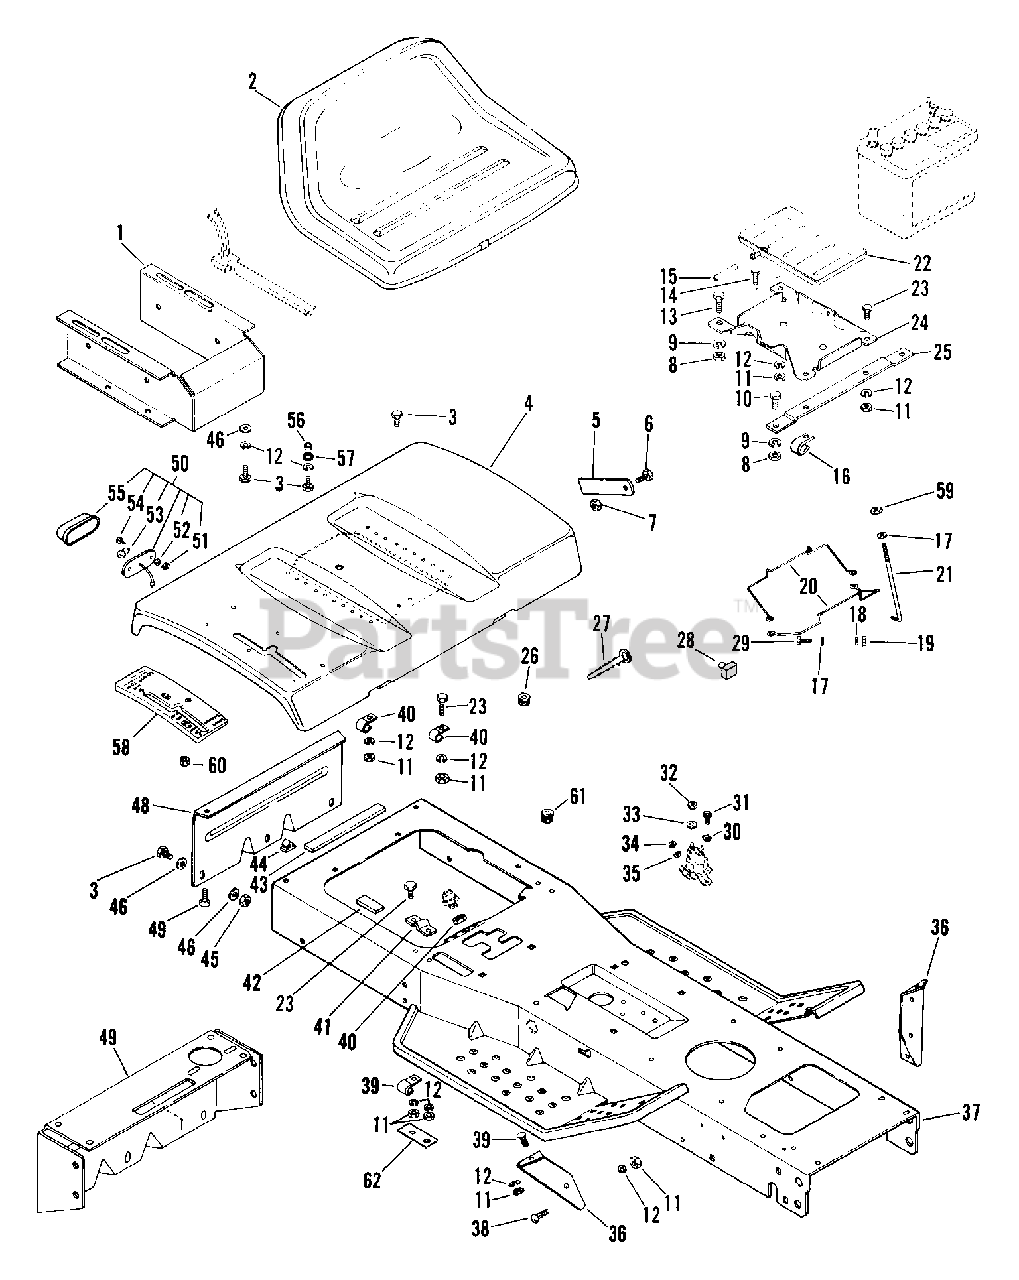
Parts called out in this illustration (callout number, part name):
1	SEAT FRAME
2	SEAT V-350
2	SEAT-V450
3	BLT-HEX .31-18X.75 PL GR5
4	REAR DECK
5	CATCH,DECK
6	BLT-HEX .38-16X.63 PL GR2
7	NUT-LK-JAM-CTR .375-16 PL
8	NUT-HEX .375-16
9	WSHR-LK .375X.115 HVY PL
10	BLT-HEX .38-16X.75 PL GR2
11	NUT-HEX .312-18
12	WSHR-LK .312X.097 PL HVY
13	BLT-HEX .38-16X1.25 PL GR 2
14	BLT-HEX .31-18X1.00 PL GR 2
15	DRAIN HOSE
16	J-CLAMP
17	WSHR-FL-STL.281X.62X.065 PL
18	WSHR-LK .250X.077 HVY PL
19	NUT-HEX .250-20 PL
20	BATTERY HOLD DOWN
21	TIE DOWN
22	BATTERY TRAY
23	BLT-HEX .31-18X.75 PL GR2
23	SCR-TAP .312-18X.50 HWH PL TR
24	BATTERY TRAY
26	GROMMET 1.0ID X 1.38 OD
27	TIE DOWN
28	INSULATOR
29	BLT-HEX .25-20X.75 PL GR2
30	WSHR-LK-EXT. 250 ID
31	SCR-TAP .250-20X.37 HWH PL TR
32	NUT-JAM .312-24 PL
33	WSHR-LK-INT .313X.030 PL
34	NUT 10-32 PL
35	WSHR-LK-EXT #10 ID X .022
36	STRUT LEFT FOOT BOARD
36	STRUT RIGHT FOOT BOARD
37	MAIN FRAME
38	BLT-RDHDSQNK .31-18X.75 SHT PL
39	J-CLAMP
40	NUT- .562-18
42	FOAM TAPE
43	FOAM TAPE
45	NUT-LK-TOP .312-18 GR C PL
46	WSHR-FL-STL .38X.875X.083 PL
47	NUT-LK-CTR .375-16 GR A PL
48	DRAW BAR
49	BLT-HEX .38-16X1.25 PL GR5
50	TAIL LIGHT ASSEMBLY W/BULLET
51	NUT-HEX 10-24 PL
52	WSHR-LK 10X.047 MED PL
54	SCR-MCH 10-24X.50 SLTR PL
55	TAIL LIGHT LENS
56	SPACER BUSHING .5 X .32 X .21
57	WSHR-FL-STL .505X.875X.024 PL
58	SHIFT INSERT
59	NUT-LK-NYL .250-20 PL
60	NUT-SELF-THRDNG FITS.25 STUDPL
61	HOLE PLUG
